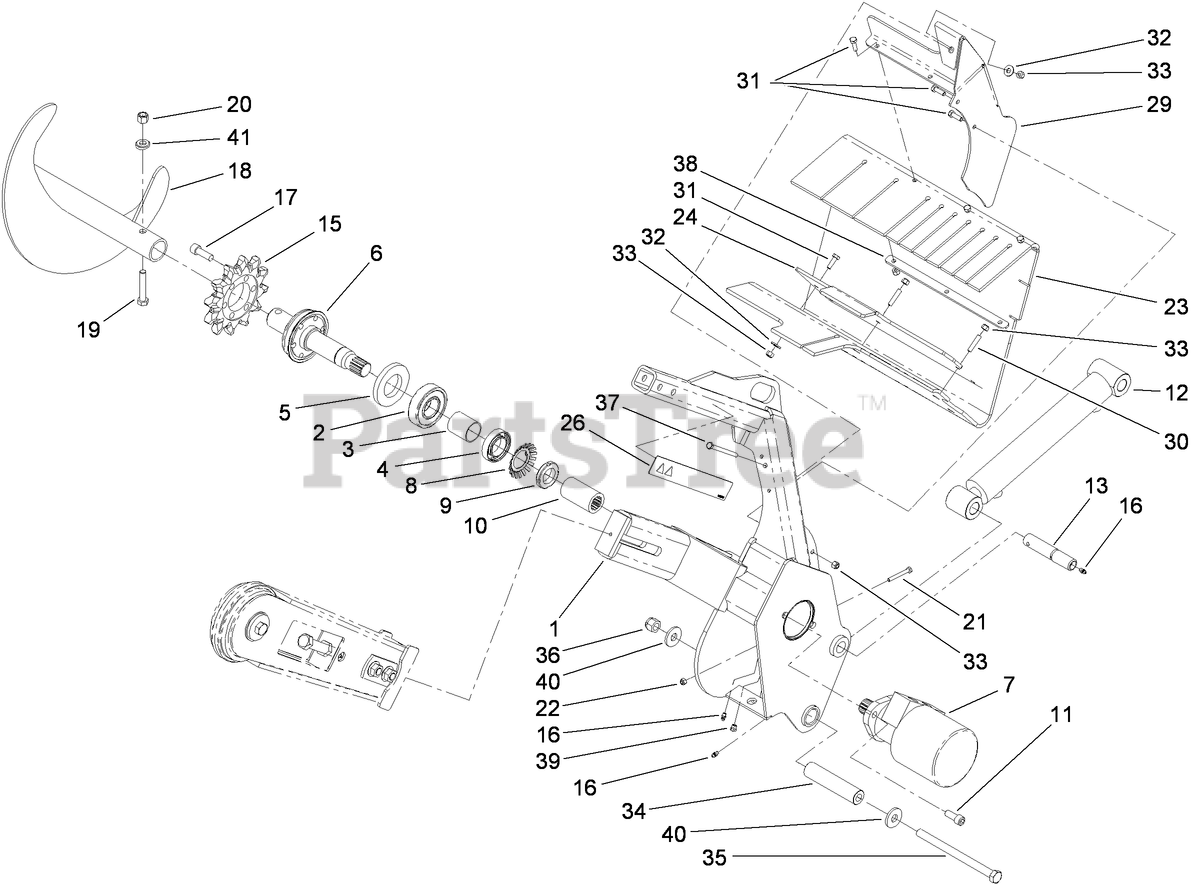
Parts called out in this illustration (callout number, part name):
1	TRENCHER HEAD ASM
2	BEARING-BALL
3	SPACER
4	BEARING-BALL
5	SEAL-GREASE
6	SHAFT-TRENCHER
7	HYDRAULIC MOTOR ASM
8	LOCKWASHER-BEARING
9	LOCKNUT-BEARING
10	COLLAR-SPLINED
11	SCREW-HSH
12	HYD CYLINDER ASM
13	PIN-PIVOT
15	SPROCKET-TRENCHER
16	FITTING-GREASE
17	SCREW-HSH
18	TRENCHER AUGER ASM
19	SCREW-HH
20	NUT-LOCK, NI
21	SCREW-HH
22	NUT-LOCK, NI
23	SHIELD-DIRT
24	BAR-CLAMP
26	DECAL-DANGER
29	BRACKET-SHIELD
30	SCREW-HSH
31	SCREW-HH
32	WASHER-FLAT
33	NUT-LOCK, NI
34	SPACER-PIVOT
35	BOLT-HH
36	NUT-LOCK, NI
37	SCREW-HH
38	PLATE-STRAP, SHIELD
39	FITTING-LUBE
40	WASHER-HARDENED
41	WASHER-SADDLE
